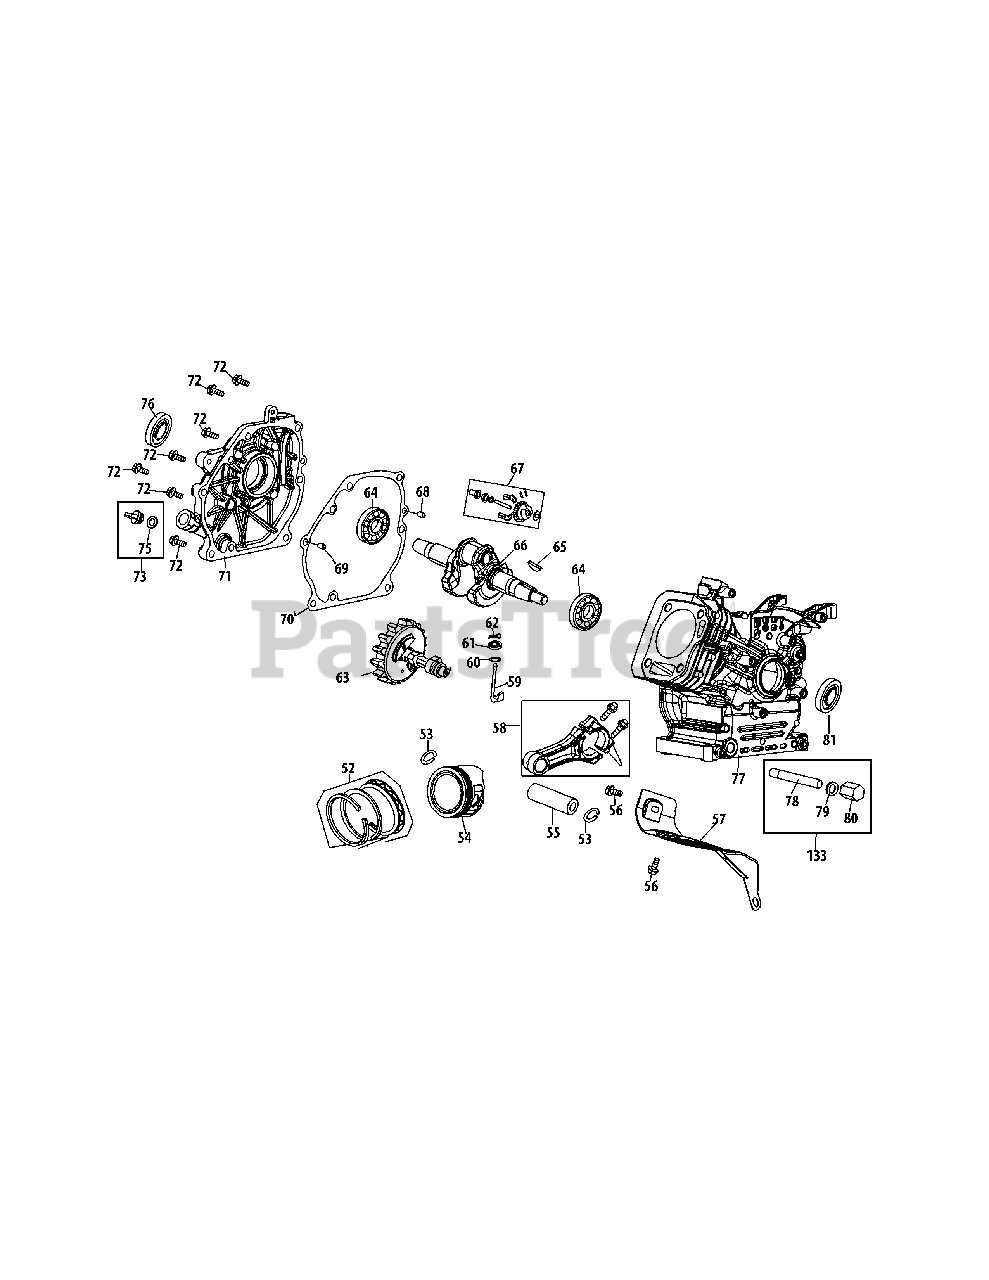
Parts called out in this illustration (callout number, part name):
52	Piston Ring Set
53	Piston Pin Snap Ring
54	Piston
55	Piston Pin
56	Bolt M6×12
57	Air Shield
58	Connecting Rod Assembly
59	Governor Arm Shaft
60	Washer 5.2×1.9
61	Governor Seal
62	Cotter Pin
63	Camshaft Assy.
64	Radial Ball Bearing, 6205
65	Woodruff Key
66	Crankshaft Kit
67	Governor Gear/Shaft Assembly
68	Dowel Pin 7×14
69	Dowel Pin 9×14
70	Crankcase Cover Gasket
71	Cover Comp, Crankcase
72	Bolt M8×32
73	Oil Fill Plug Assembly
75	O-Ring 15.8×2.5
76	Oil Seal, 25×41.25×6
77	Crankcase Kit
78	Oil Drain Pipe Assy.
79	Washer 10×16×1.5
80	Oil Drain Plug
81	Oil Seal 25×41.25×6
133	Oil Drain Assembly
